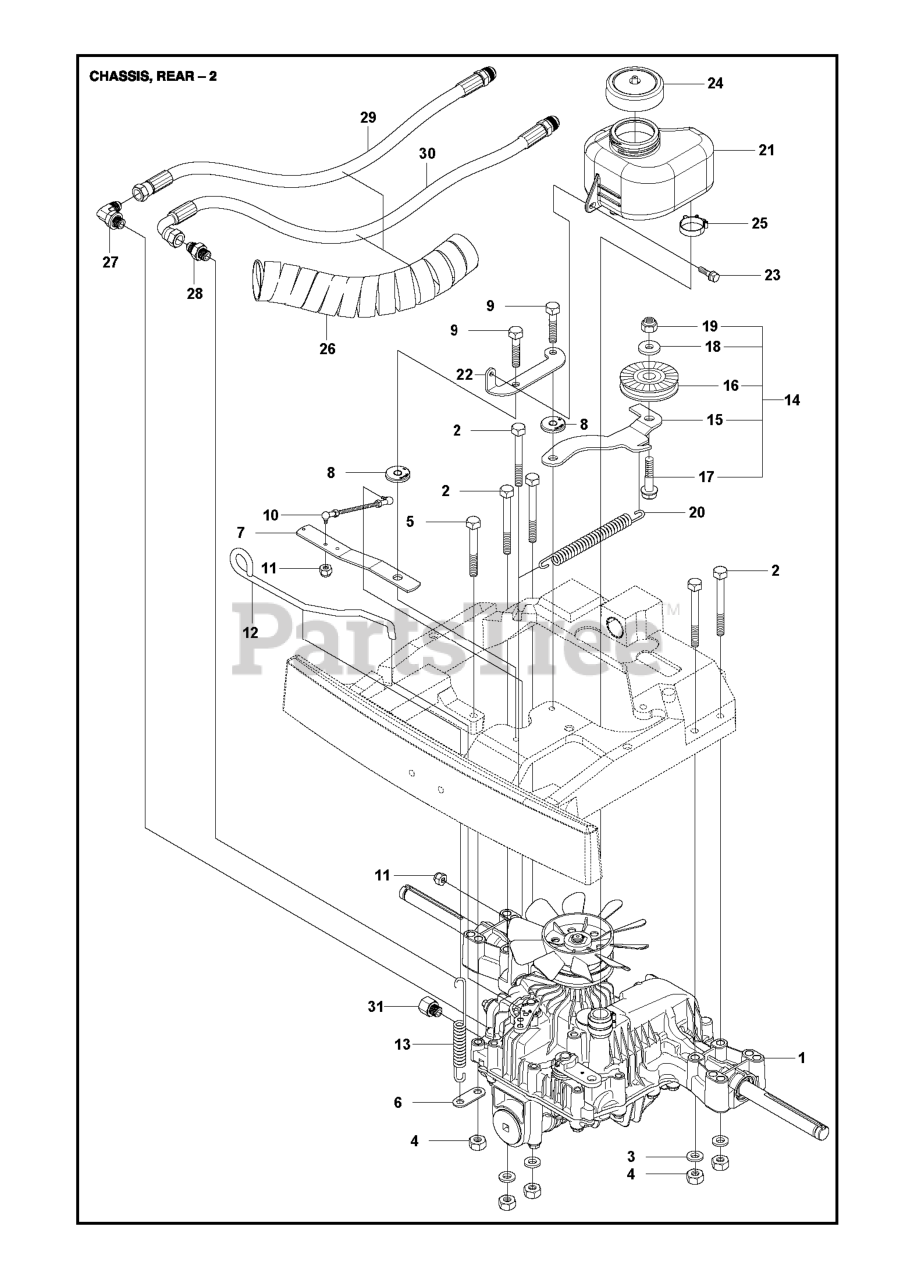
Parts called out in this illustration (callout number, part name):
3	WASHER BRB 8.4X17
4	NUT
11	LOCKNUT M5
15	BELT TENSIONER ARM
19	LOCKNUT M8
20	SPRING
21	EXPANSION TANK RIDER EXTENDED
21	TANK
25	HOSE CLAMP 20-32
26	HOSE GUARD D=43 L=400
